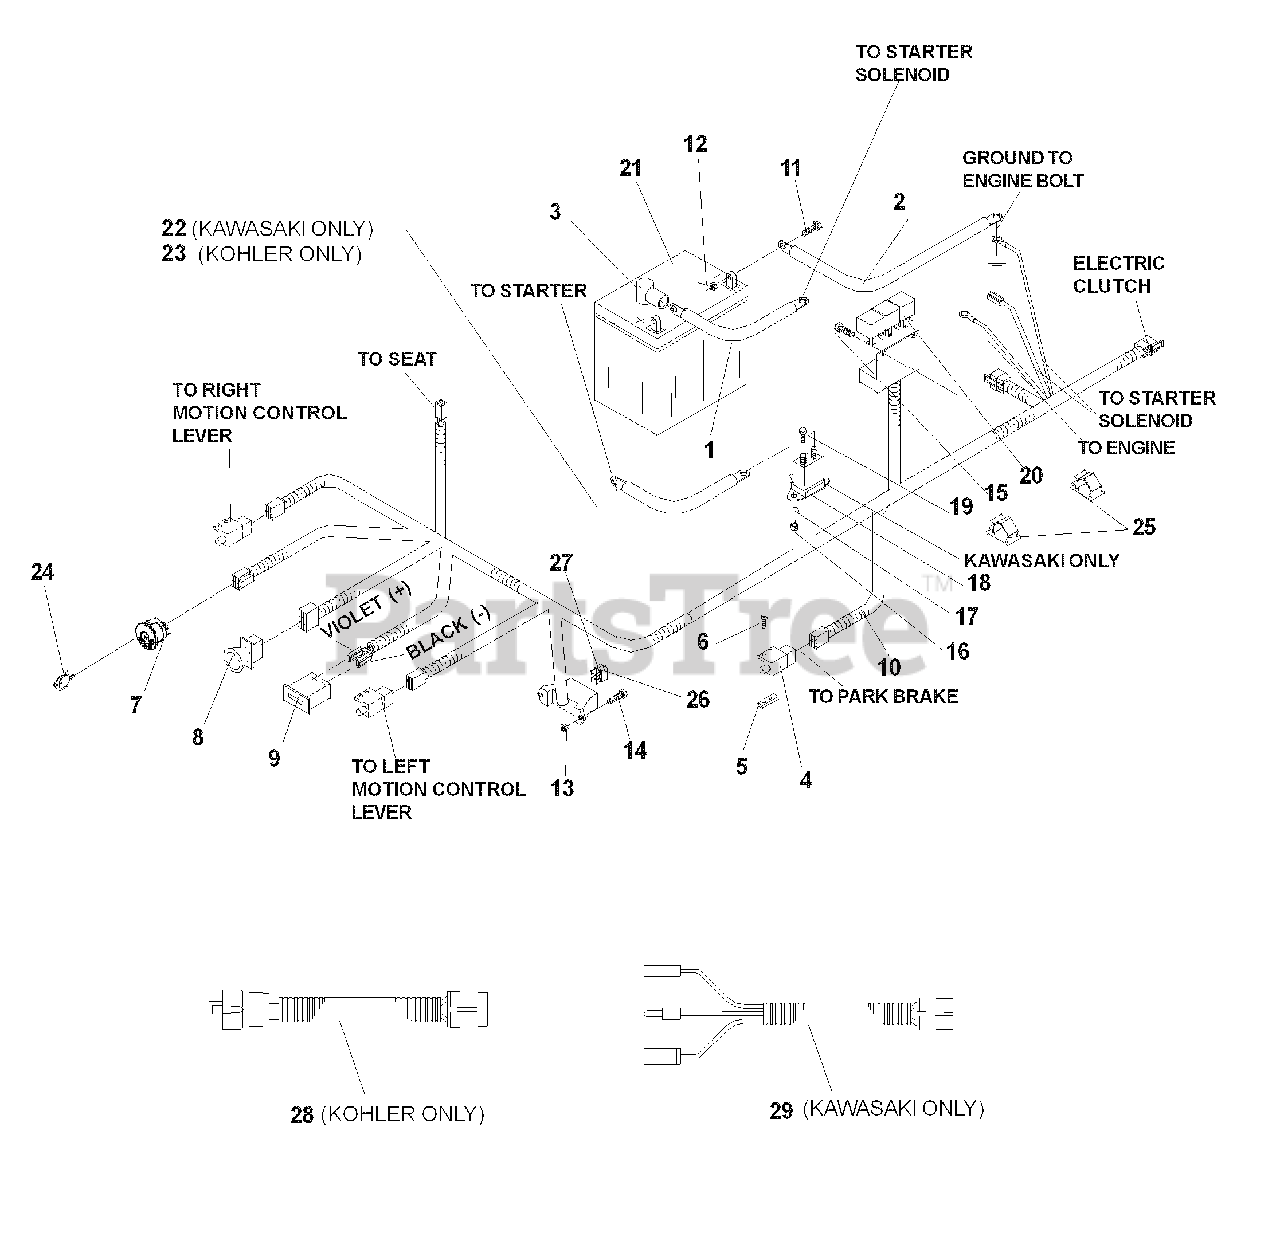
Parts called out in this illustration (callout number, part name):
1	POSITIVE CABLE
2	NEGATIVE CABLE
4	INTERLOCK SWITCH
5	TAPPED PLATE
6	SCREW, #10-24 x 5/8
7	IGNITION SWITCH
8	BLADE SWITCH
9	HOUR METER
10	FRAME HARNESS
11	HCS, 5/16C x 3/4
12	NUT, 5/16C, NYLOC
13	NUT, #10-24, NYLOC
14	SCREW, #10-24 x 7/8
15	SCREW, #10-24 x 5/8, WSH HD
16	NUT, 1/4C, CENTERLOCK
17	LOCKWASHER, 1/4
18	SOLENOID KAWASAKI ONLY
19	HCS, 1/4C x 5/8
21	BATTERY, DRY
22	CABLE POSITIVE, KAWASAKI ONLY
23	CABLE POSITIVE, KOHLER ONLY
24	KEY, PADDED
25	PUSH MOUNT WIRE CLIP
26	FUSE, 7.5 AMP, 32 VOLT, ATO
27	FUSE, 20 AMP, 32 VOLT, ATO
28	PIGTAIL, KOHLER ONLY
29	PIGTAIL, KAWASAKI ONLY
